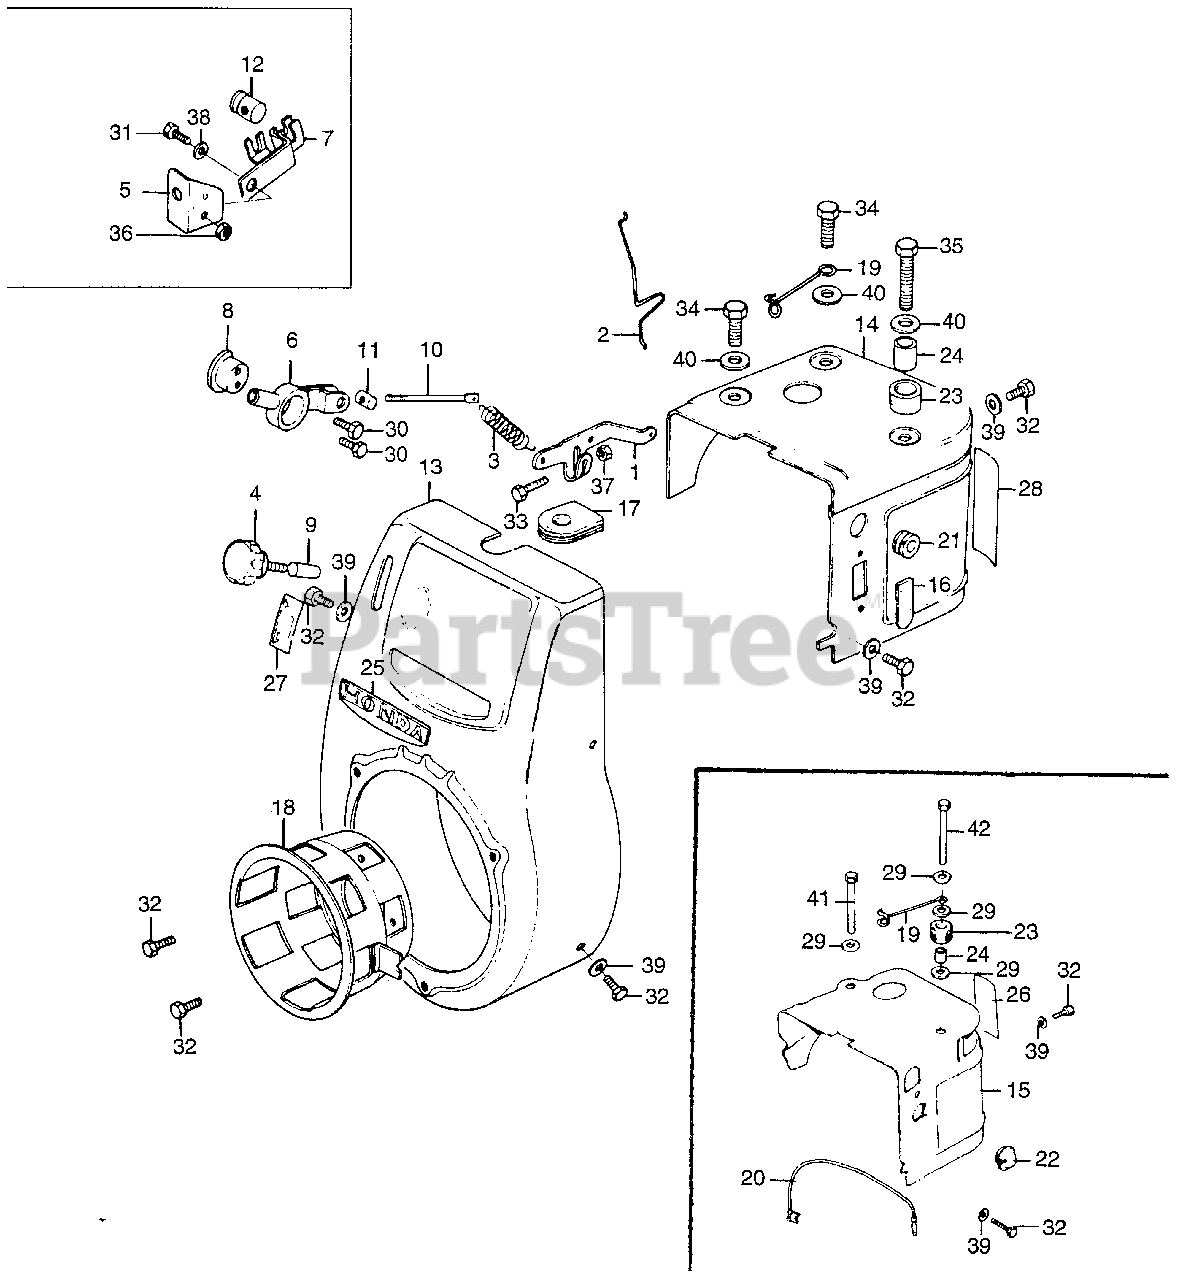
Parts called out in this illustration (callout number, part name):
1	ARM, GOVERNOR (NOT AVAILABLE)
2	ROD, GOVERNOR (NOT AVAILABLE)
3	SPRING, GOVERNOR
4	SCREW, GOVERNOR ADJUST (NOT AVAILABLE)
6	LEVER, CONTROL (NOT AVAILABLE)
8	SHAFT, CONTROL
9	BUSH, CONTROL (NOT AVAILABLE)
10	ROD, ADJUSTING
11	JOINT, ADJUSTING ROD (NOT AVAILABLE)
13	COVER, FAN *R8* (BRIGHT RED) (NOT AVAILABLE)
14	COVER, SIDE *R8* (BRIGHT RED) (NOT AVAILABLE)
16	DEFENDER, SIDE COVER
17	GROMMET, WIRE
18	PULLEY, STARTER
19	CLAMP, IGNITION WIRE (NOT AVAILABLE)
21	GROMMET A, SIDE COVER (NOT AVAILABLE)
23	RUBBER, STOPPER (NOT AVAILABLE)
24	COLLAR, DISTANCE
25	EMBLEM (NOT AVAILABLE)
27	PLATE, THROTTLE (ENGLISH/FRENCH)
28	MARK, OIL CAUTION (NOT AVAILABLE)
30	BOLT, HEX. (5X8)
32	BOLT, HEX. (6X12)
33	BOLT, HEX. (6X16)
34	BOLT, HEX. (8X16)
35	BOLT, HEX. (8X32)
37	NUT, HEX. (6MM)
39	WASHER, PLAIN (6MM)
40	WASHER, PLAIN (8MM)
